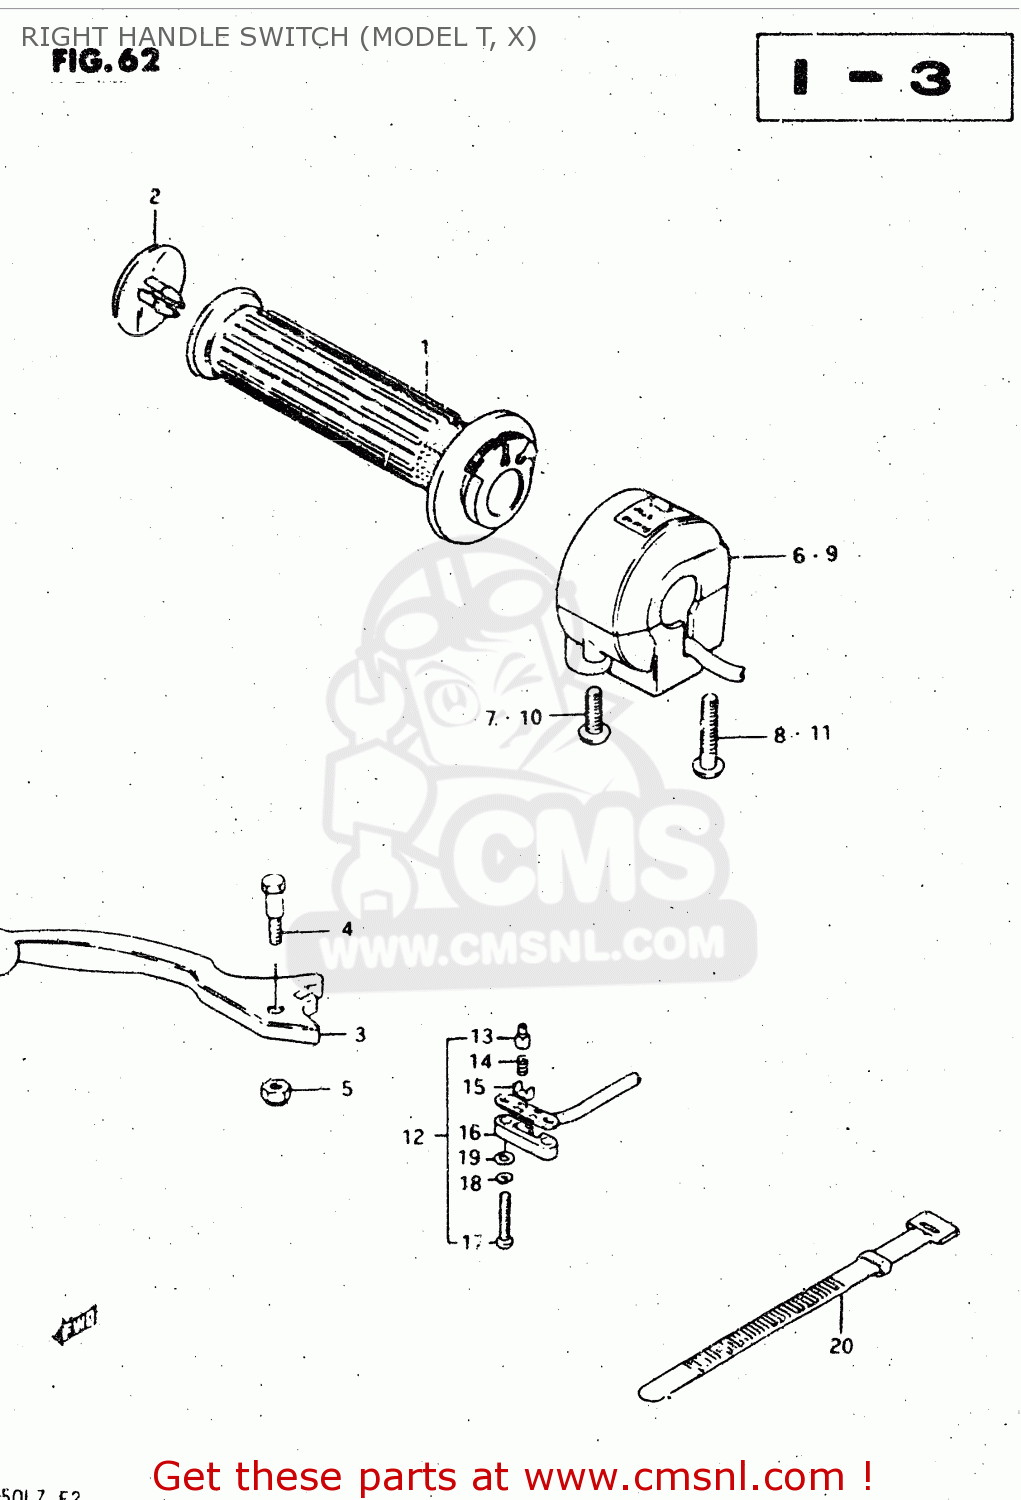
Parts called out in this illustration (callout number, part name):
1	GRIP,THROTTLE
2	CAP,GRIP END
3	LEVER,BRAKE
4	BOLT
5	NUT 6MM
6	SWITCH ASSEMBLY,HANDLE,RIGHT
7	SCREW
8	SCREW
9	SWITCH ASSY, HANDLE RH
10	SCREW
11	SCREW
12	SWITCH ASSEMBLY
13	HOLDER
14	SPRING
15	PLATE
16	COVER,FR BK TERMINAL BASE
17	SCREW
18	LOCK WASHER
19	WASHER
20	CLAMP(L:120)
